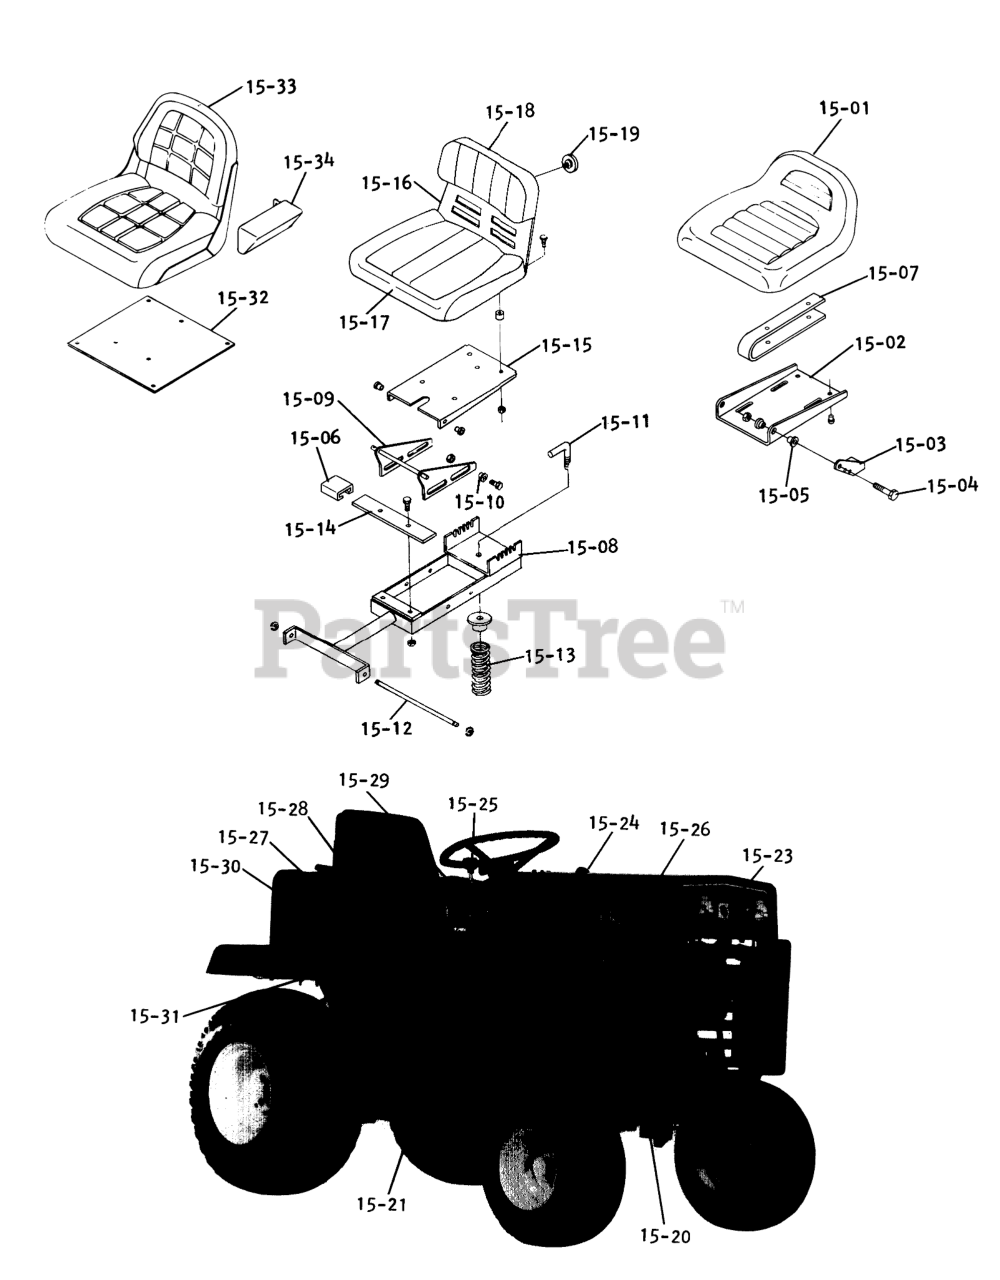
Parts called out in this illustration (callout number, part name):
14-55	Bracket
14-56	BEARING
14-57	FLANGE
14-58	ZERK 90DEGREE
14-59	SHAFT-DRIVE
14-60	Pulley
14-61	Assembly Bearing
14-62	Bearing Bracket
14-63	BELT PTO
14-64	QUICK COUPLER ASSY
15-01	Seat, D-160
15-02	Plate Seat Pivot
15-03	Bracket-Pivot RH
15-04	Bolt
15-05	Bushing
15-06	BUMPER-RUBBER
15-07	Spring
15-08	Seat Pivot Assembly
15-09	Seat Adjustment Assembly
15-10	SPACER
15-11	Rod-Adjusting
15-12	Rod-Pivot
15-13	Spring
15-14	Bar-Seat Stop
15-15	Seat Ad justing Plate
15-16	Seat Base
15-17	Seat Cushion
15-18	Back Cushion
15-19	Wing Head Stud
15-20	Decal
15-21	Decal-"D-160 Automatic"
15-22	Decal-Tach-a-matic
15-23	Decal
15-24	Decal-Clutch Knob
15-25	Sleeve
15-26	Decal
15-28	Decal-Caution
15-29	Decal
15-30	Decal-Maintenance
15-31	Reflector
15-32	Seat Plate, D-200
15-33	Seat
15-34	Arm Rest-R.H.
15-35	Decal-Parking Brake
